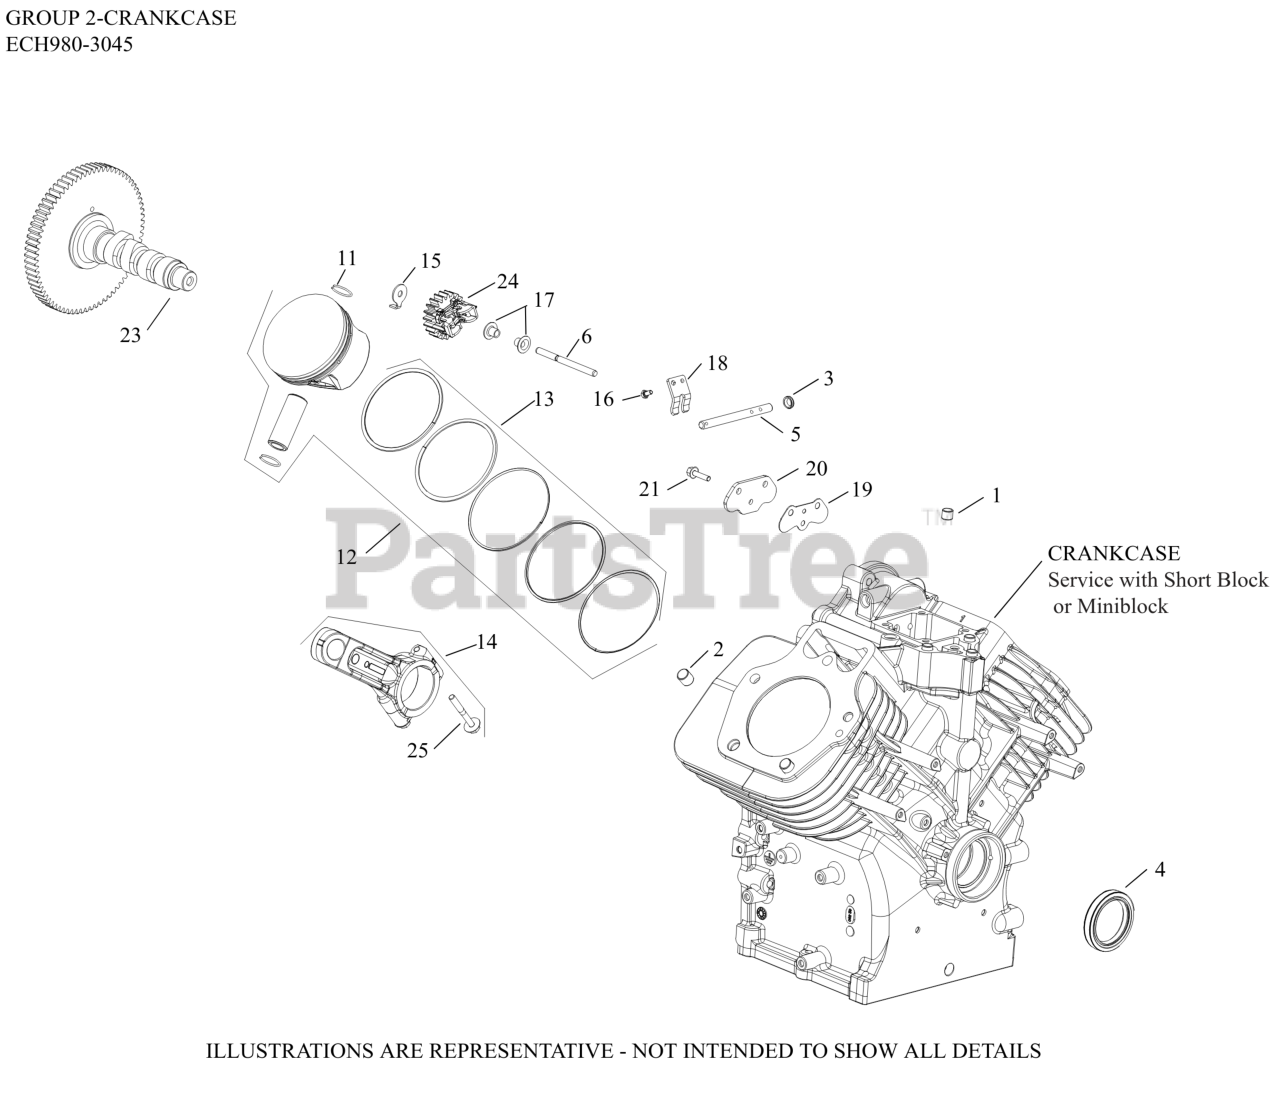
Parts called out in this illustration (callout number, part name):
2	PIN, LOCATING
3	SEAL, GOVERNOR CROSS SHAFT
4	SEAL, OIL FW SIDE, BLACK
5	SHAFT, GOVERNOR CROSS
6	SHAFT, GOVERNOR GEAR
11	RETAINER, PISTON PIN
12	RING, SET PISTON (STD)
13	KIT, PISTON (STD)
13	KIT, PISTON (0.25 OS)
13	KIT, PISTON (0.50 OS)
14	CONNECTING ROD ASSEMBLY
15	TAB, LOCKING
16	SCREW, HEX HEAD
17	PIN, GOVERNOR REGULATING
18	YOKE, GOVERNOR
19	GASKET, LIFTER FEED COVER
20	KIT, COVER, LIFTER FEED
21	SCREW, HEAVY HEX FLANGE
23	KIT, CAMSHAFT
24	KIT, GOVERNOR GEAR
25	KIT, ROD BOLTS
